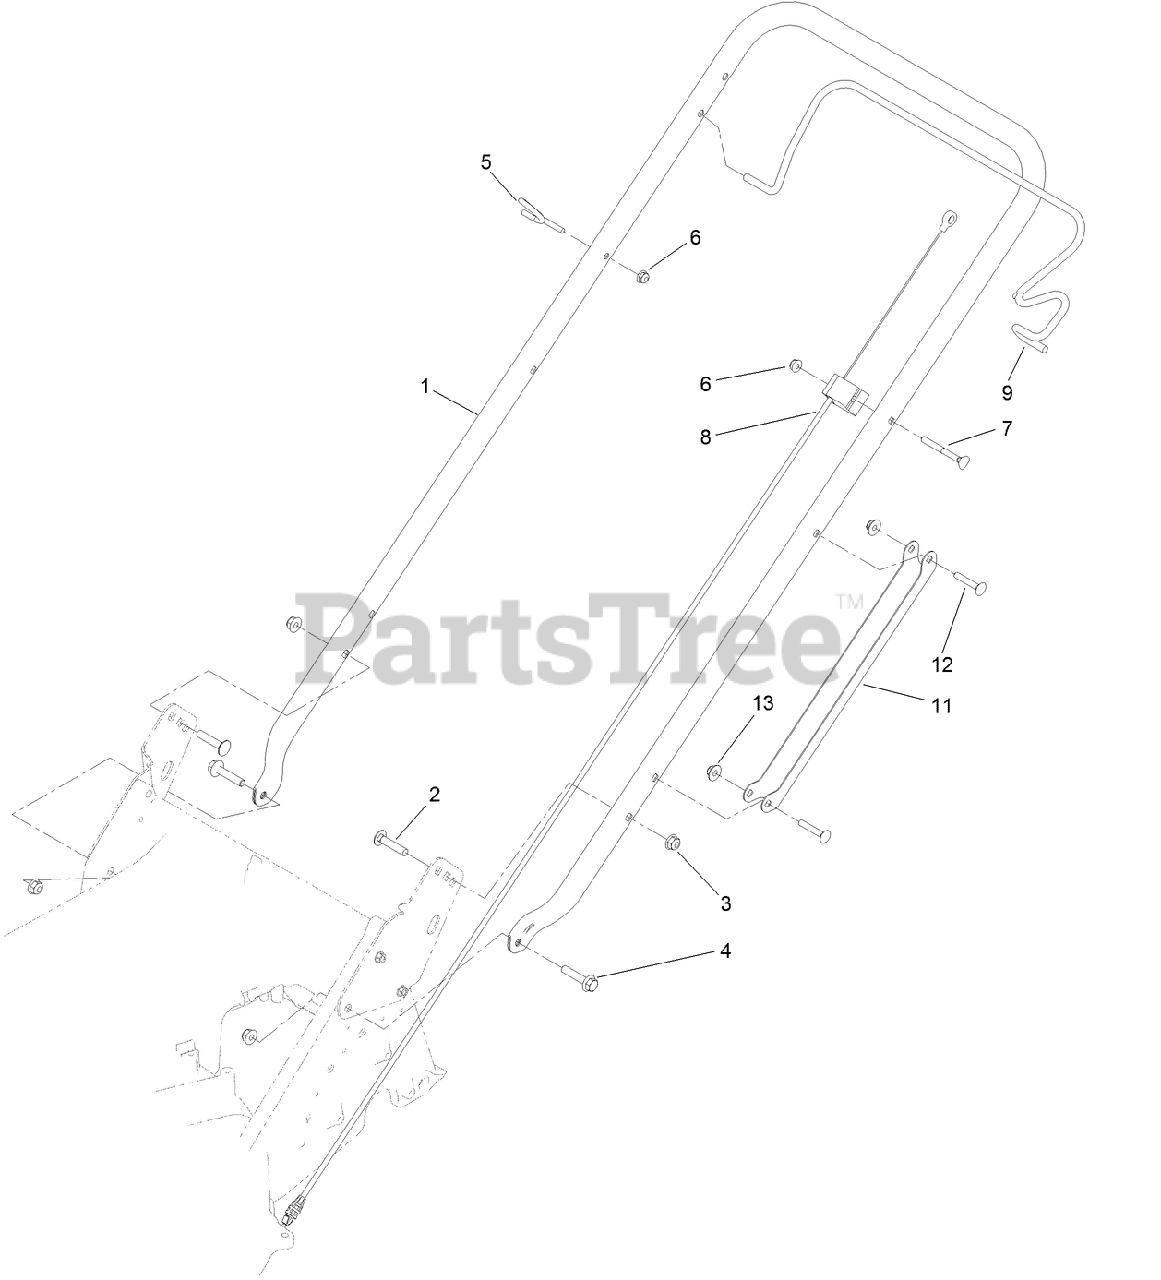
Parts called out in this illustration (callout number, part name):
2	BOLT-CARR
3	NUT-HF, NI
4	SCREW-HHF
5	GUIDE-ROPE
6	NUT-HF
7	SCREW-HANDLE
8	CABLE-BRAKE
9	BAIL-BRAKE
11	GUARD-CABLE, HANDLE
12	SCREW-CARR
13	NUT-HF
